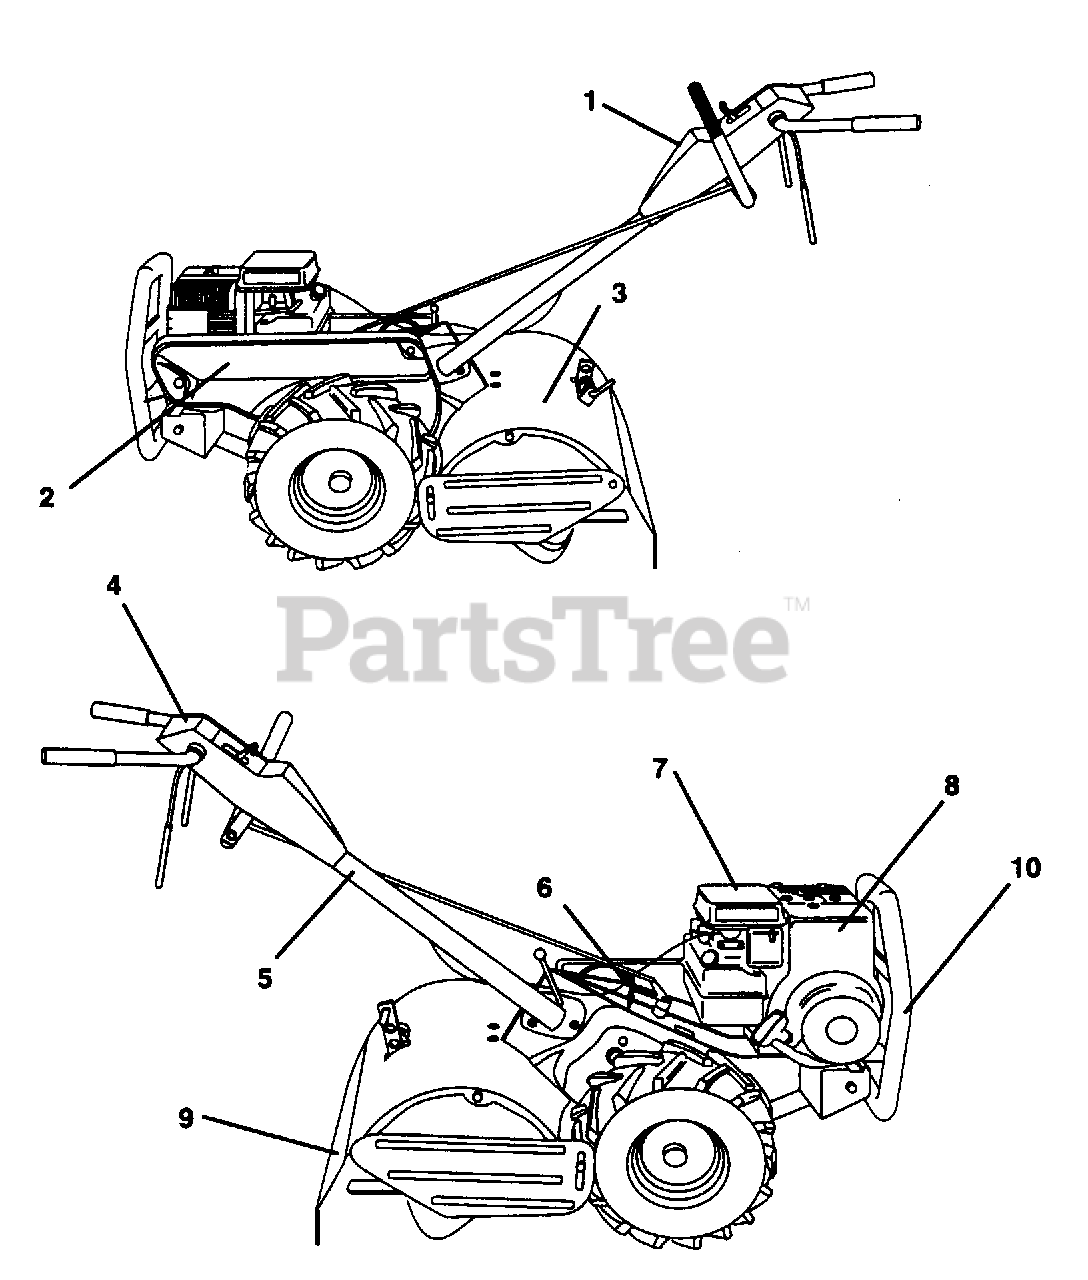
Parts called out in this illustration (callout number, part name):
1	Decal, Logo
2	Decal, Logo
3	Decal, Logo
4	Decal, Instruction, Tilling (AYP part number)
5	Decal, Hand Placement (AYP part number)
6	Decal, Shift Indicator (AYP part number)
7	Decal, Caution (AYP part number)
8	Decal, Briggs & Stratton (AYP part number)
9	Decal, Warning, Rotating Tines (AYP part number)
10	Decal, Bumper/Grille
